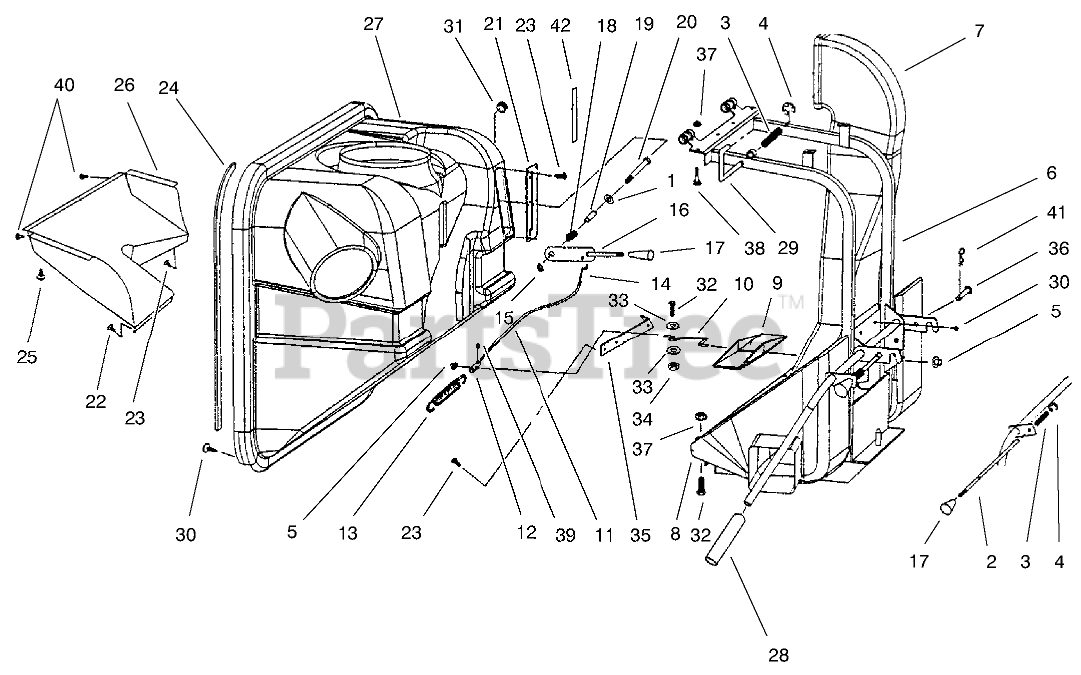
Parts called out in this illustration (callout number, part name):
1	WASHER-FLAT
2	PIN-HITCH
3	SPRING
4	RING-RETAINER
5	WASHER-CAP
6	FRAME
7	DOCK-AIR
8	HOPPER-BOTTOM
9	DOOR-AIR
10	LEVER-DOOR
11	SHIELD-CABLE
12	END-CABLE
13	SPRING
14	CABLE
15	NUT-HF
16	LEVER-DRAFT
17	KNOB-OVAL
18	SPRING
19	SLEEVE
20	SCREW-HH
21	Plate-Lever (Incl. Ref. #42)
22	SCREW-PPH
23	SCREW-TAP
24	SEAL-STRIPPING
25	Screw-Hex Washer Hd.
26	FILTER
27	HOPPER-FRONT
28	GRIP-HANDLE
30	SCREW-HWH, THREAD FORMING
31	CAP-RUBBER
32	SCREW-HH
33	WASHER-PLAIN
34	NUT-HEX
35	BRACKET-REINFORCING
36	PIN-HITCH
37	NUT-HF
38	Bolt-Carriage
39	SCREW-SET, HSH
40	RIVET-BLIND
41	HAIRPIN
42	Decal-Air Direction
